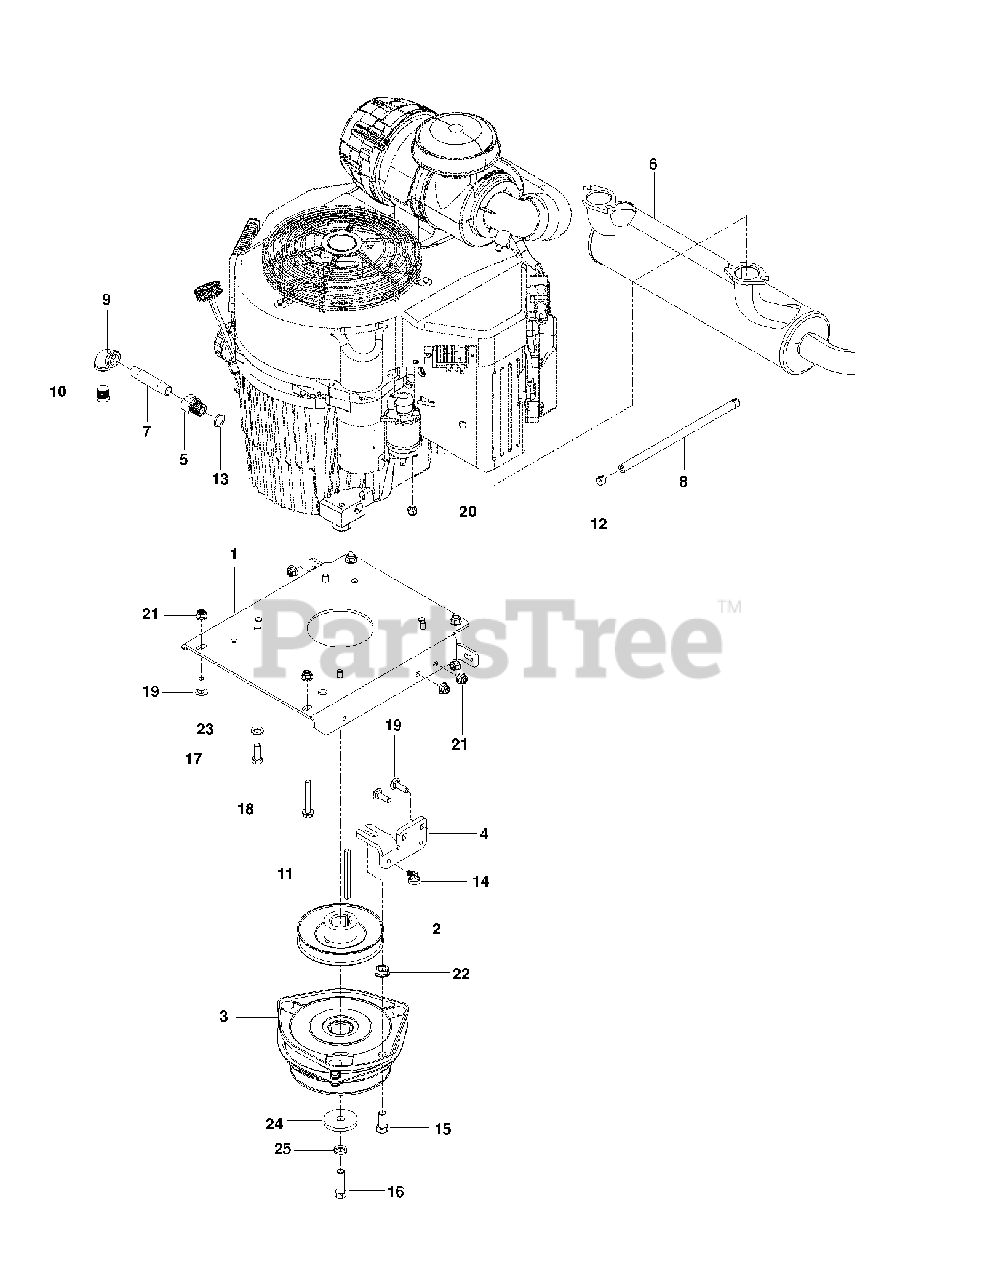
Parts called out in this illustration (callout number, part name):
1	PLATE, ENGINE, BLACK
2	PULLEY, ENGINE
3	CLUTCH, GT3.5
4	STOP, CLUTCH, OGURA
5	ADAPTER, OIL DRAIN
6	MUFFLER, 29HP KAW FX751V-850V
7	PIPE NIPPLE 3/8 X 3
8	GAS LINE 10"
9	90 DEG.ELBOW 3/8NPT
10	PLUG, DRAIN 3/8 NPTF
11	KEY, 1/4 SQ X 3.5
12	HOSE CLAMP
14	TIE WRAP, 8-3/8", W/CLIP
15	HCS 7/16-14 X 1 GR 5 ZD
16	HCS 7/16F X 1 1/2
17	HCS 3/8C X 1
18	HHFS 5/16-18 X 2.25 GD 5
19	RHSNB 5/16C X 1
20	NUT M8-1.25 TOP NYL GR10 ZD
21	5/16-18 NYLOC FLANGE NUT
22	NUT 7/16C WHIZ
23	WASHER, 3/8 DISC SPRING SPEC
24	BLADE WASHER
25	WASHER 7/16 LOCK
